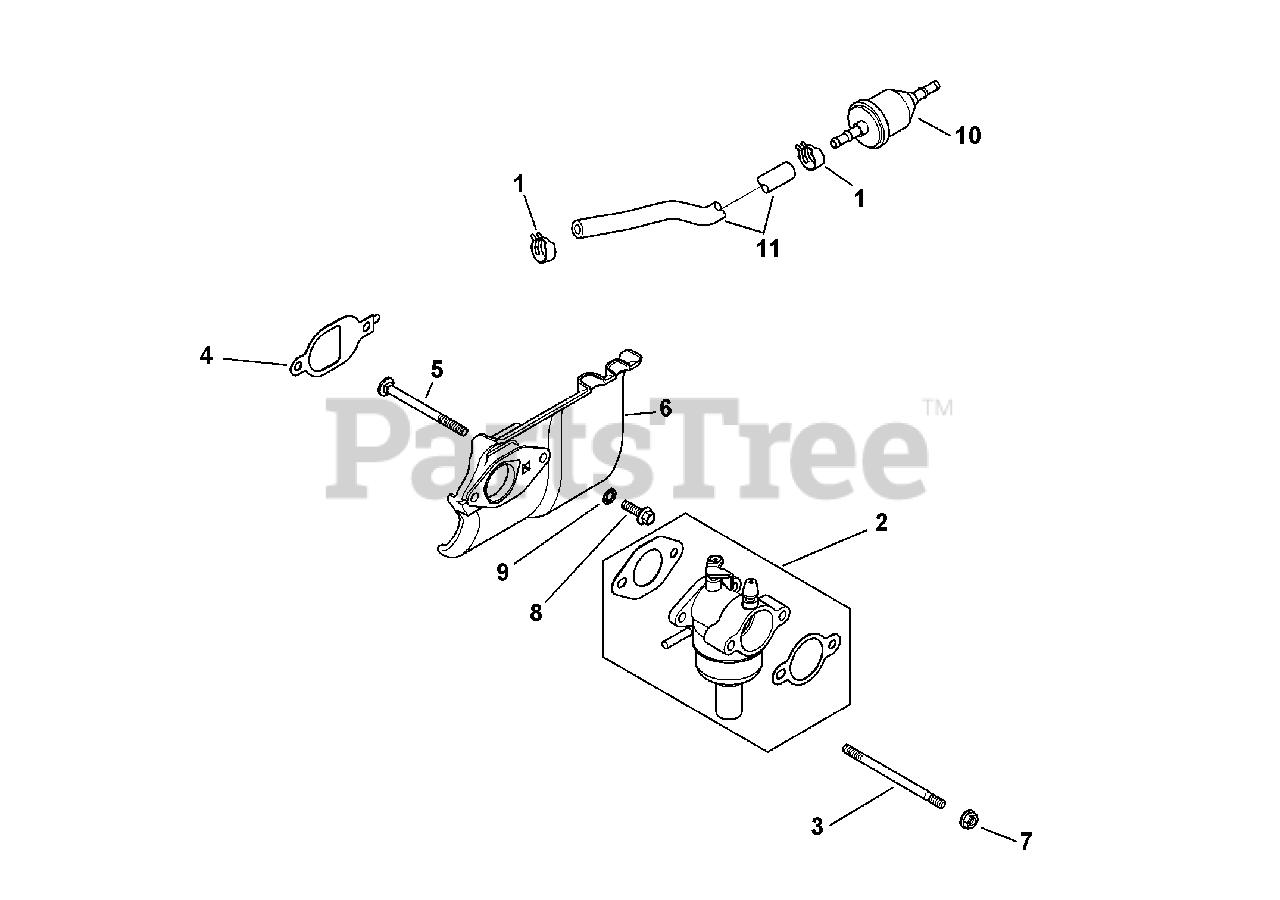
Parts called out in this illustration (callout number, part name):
1	Hose Clamp, 1/2
2	Carburetor Kit
3	Stud, M6 X 1.0 X 100
4	Heat Deflector Gasket
5	Carburetor Stud
6	Heat Deflector Kit
7	Flange Nut, M6 X 1.0
8	Flange Screw, M6 X 1.0 X 20
9	Int. Tooth Lock Washer, 1/4
